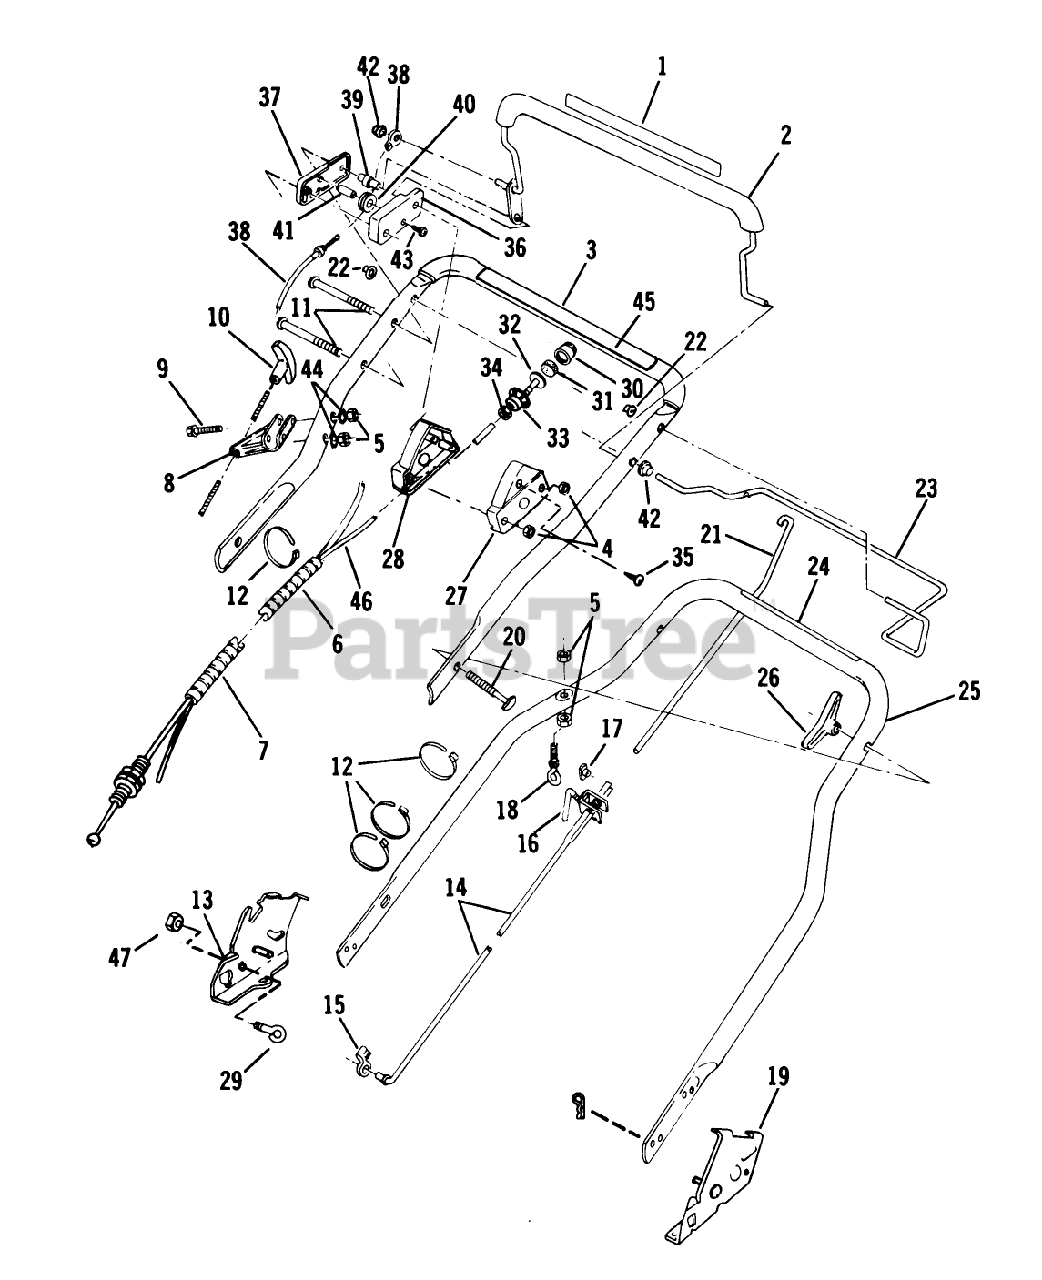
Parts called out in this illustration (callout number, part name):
4	NUT C/LOCK E
5	LOCKNUT E
10	HANDLE,STARTER
14	Control Rod Ass-y.
15	CLIP
18	EYE BOLT WAS MFG
20	BOLT QUALITY
23	LEVER
26	NUT-WING
31	FILTER S
34	LOCKNUT S
35	SCREW LAWRENCE
38	CONTROL CABLE WES
39	COLUMN
41	PIN SKF
43	SCREW
44	WASHER
47	LOCKNUT E
49	HAIR PIN
